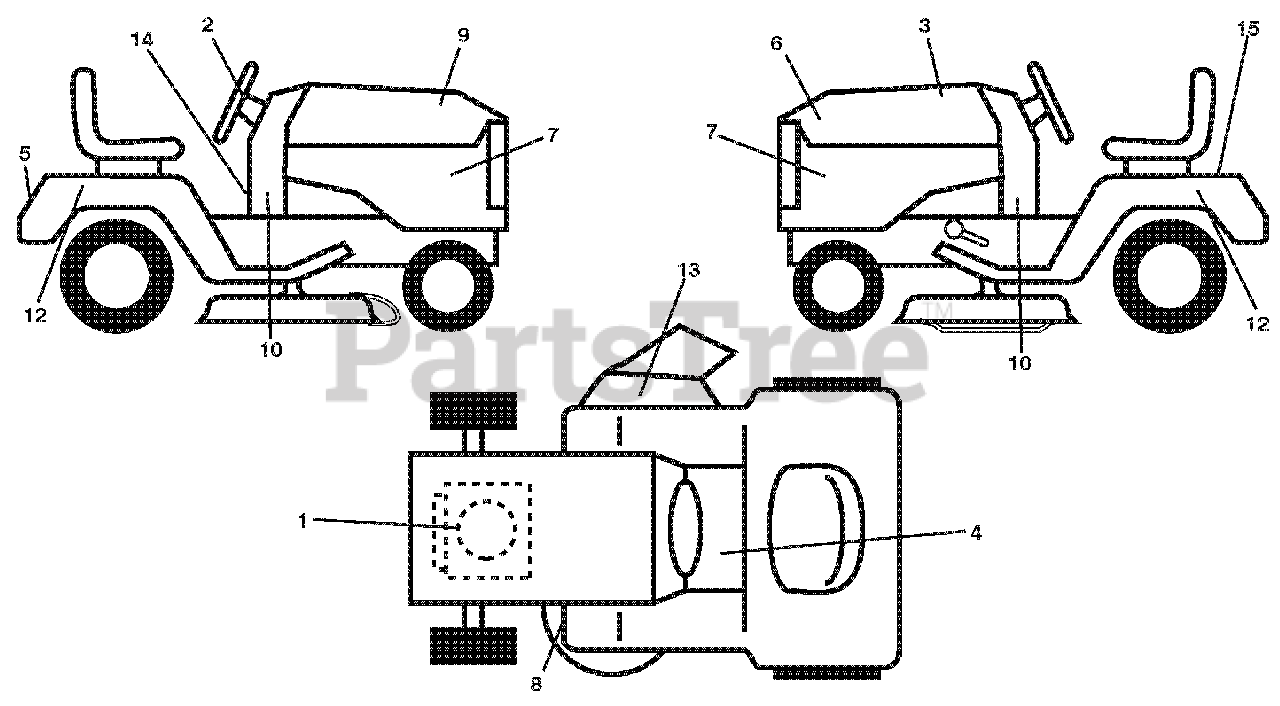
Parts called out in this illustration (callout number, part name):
2	Decal, Ins Str Wh
3	DECAL.REPLACEMENT
4	DECAL.FENDER
5	DECAL.FENDER.REAR.ARIENS
6	DECAL.HOOD.LH
7	DECAL.SDPNL.PWRDBY B&S.ARIENS
8	DECAL.V-BELT.SCH.
9	DECAL.HOOD.RH
10	DECAL, DASH LOWER
12	DECAL.FENDER.SD.GEAR.DR
13	DECAL DECK/DEFLECT. WARNING
14	DECAL.WARNING.START
15	DECAL.BAT.DAN/POI P/L SYM.WPN
